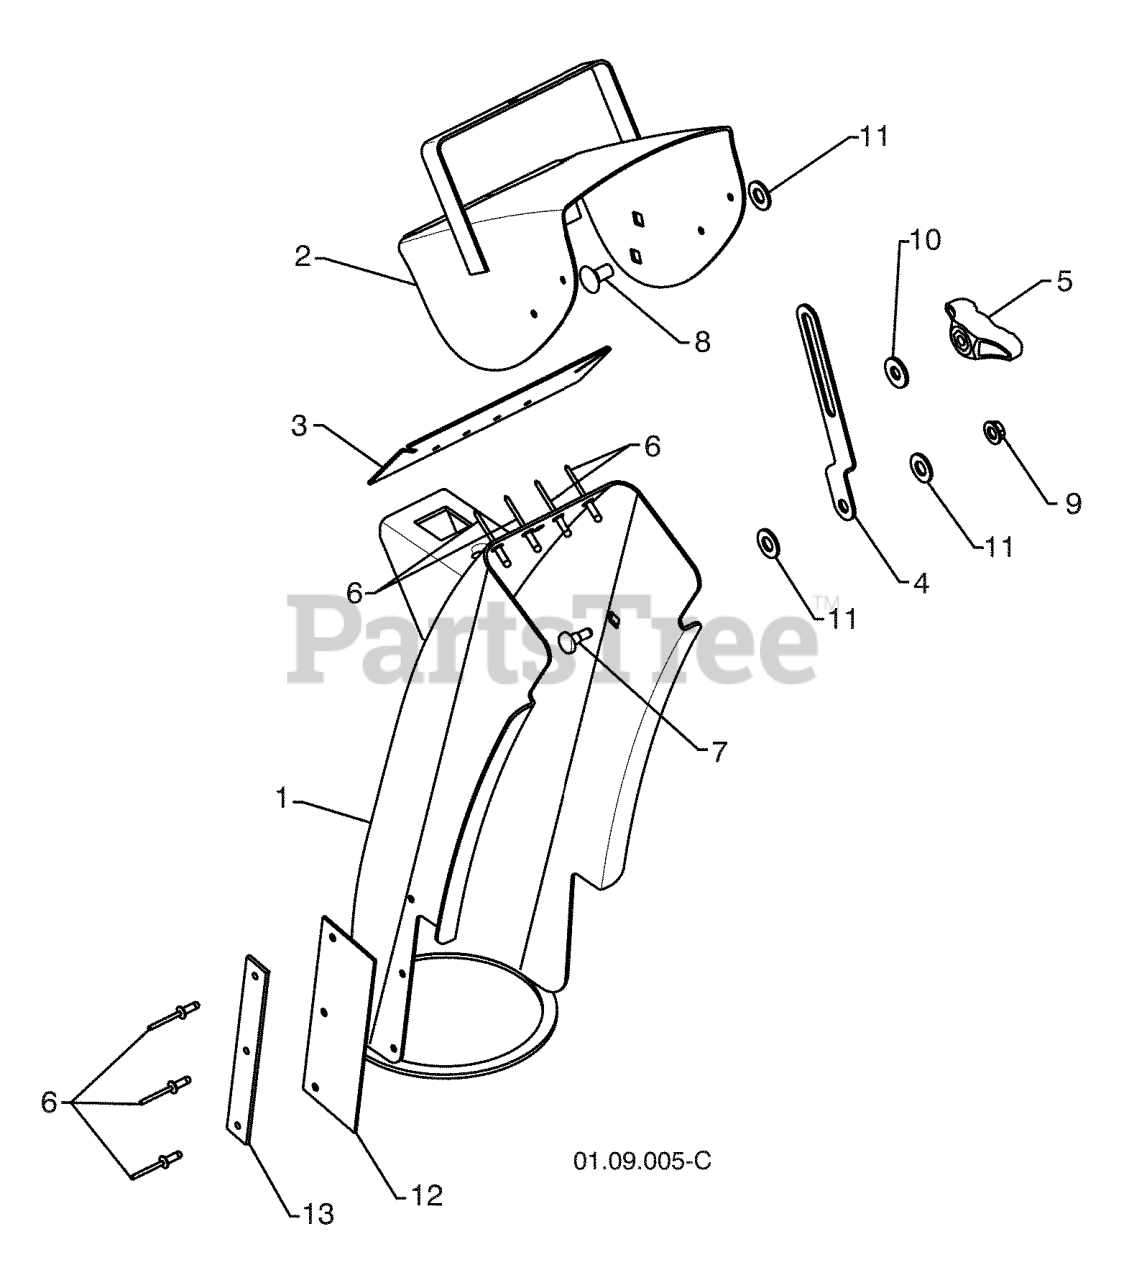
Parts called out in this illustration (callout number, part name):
1	CHUTE.WELDMENT
2	DEFLECTOR.WELDMENT.PNT.ORANGE
3	SEAL.DEFLECTOR
4	STRAP, CHUTE
5	KNOB, DEFLECTOR
6	RIVET BLIND
7	SHOULDER BOLT
8	BOLT
9	NUT.HEX.FLANGE.1/4
10	WASHER.20X8.5
11	WASHER, NYLON FRICTION
12	SHIELD.SNOW.CHUTE
13	STRAP.SHEILD.RETAINER
